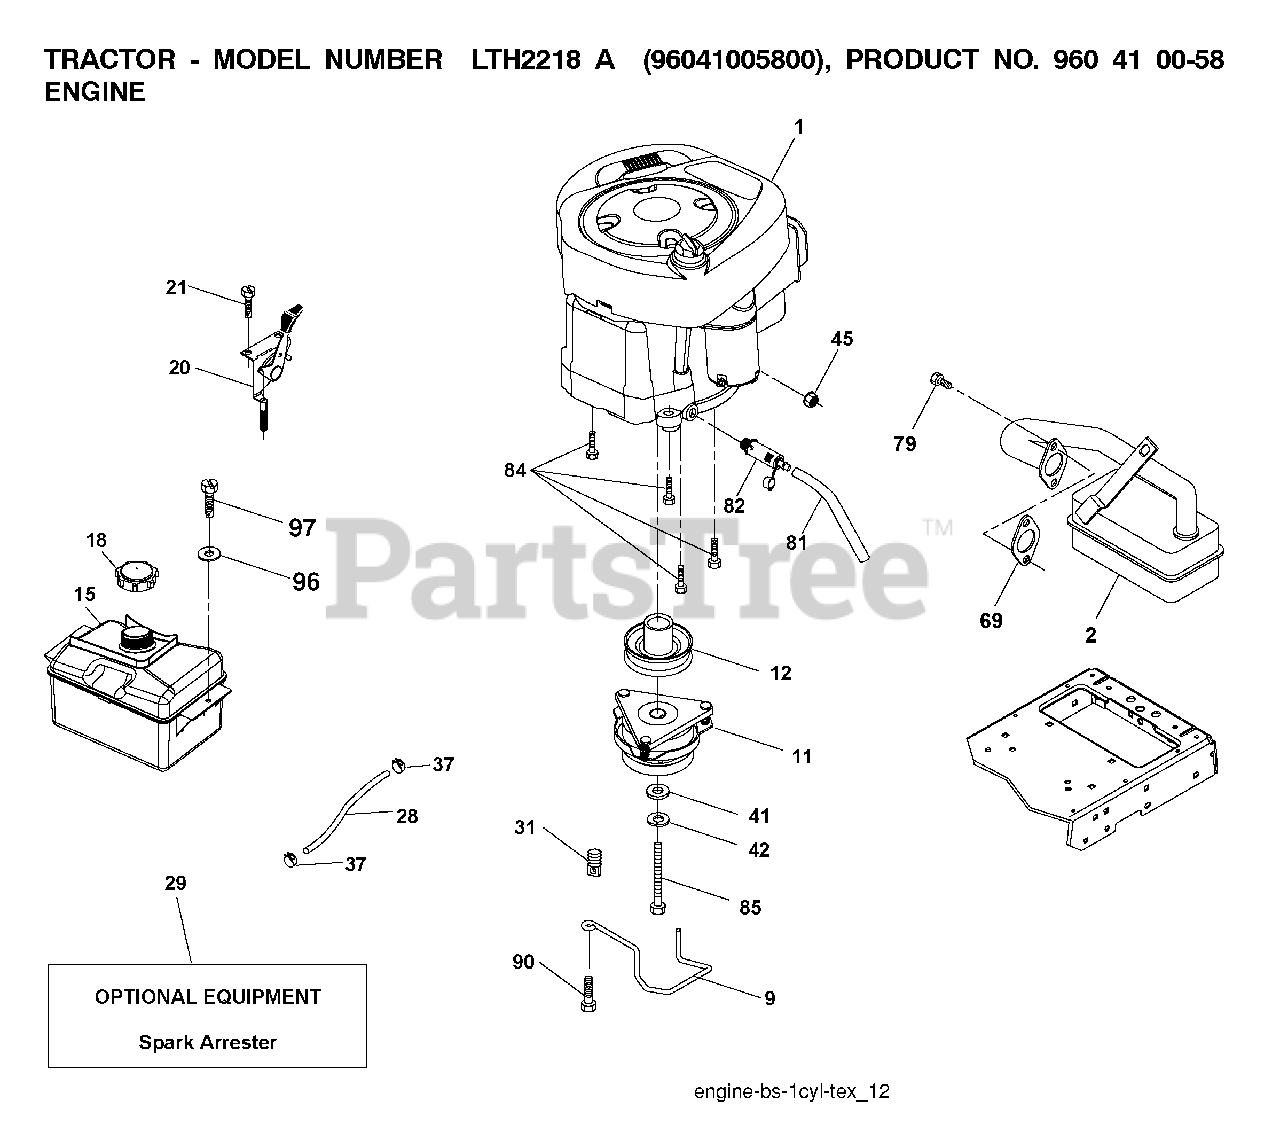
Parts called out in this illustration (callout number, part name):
9	KEEPER.BELT.ENGINE.4.2
11	CLUTCH
12	PULLEY.ENGINE.TUFFTORQ
15	TANK FUEL FRT 1.5 GAL
18	FUEL CAP
20	CONTROL.TH/CK.C.
21	SCREW
28	LINE.FUEL.20
29	ARRESTER SPARK (OPTIONAL)
31	PUSH CLIP
37	HOSE CLAMP
42	LOCKWASHER
45	NUT
69	REPL BY 532 27 22-93
79	SCREW.SOCKET HD.5/16-1
81	TUBE, DRAIN OIL ASM.
82	PLUG DRAIN OIL EASY
84	SCREW.3/8-16
85	BOLT HEX 7/16-20X4-1/4"
90	SCREW 3/8-16X1
97	SCREW HEXWSHR 1/4-20X3/4
